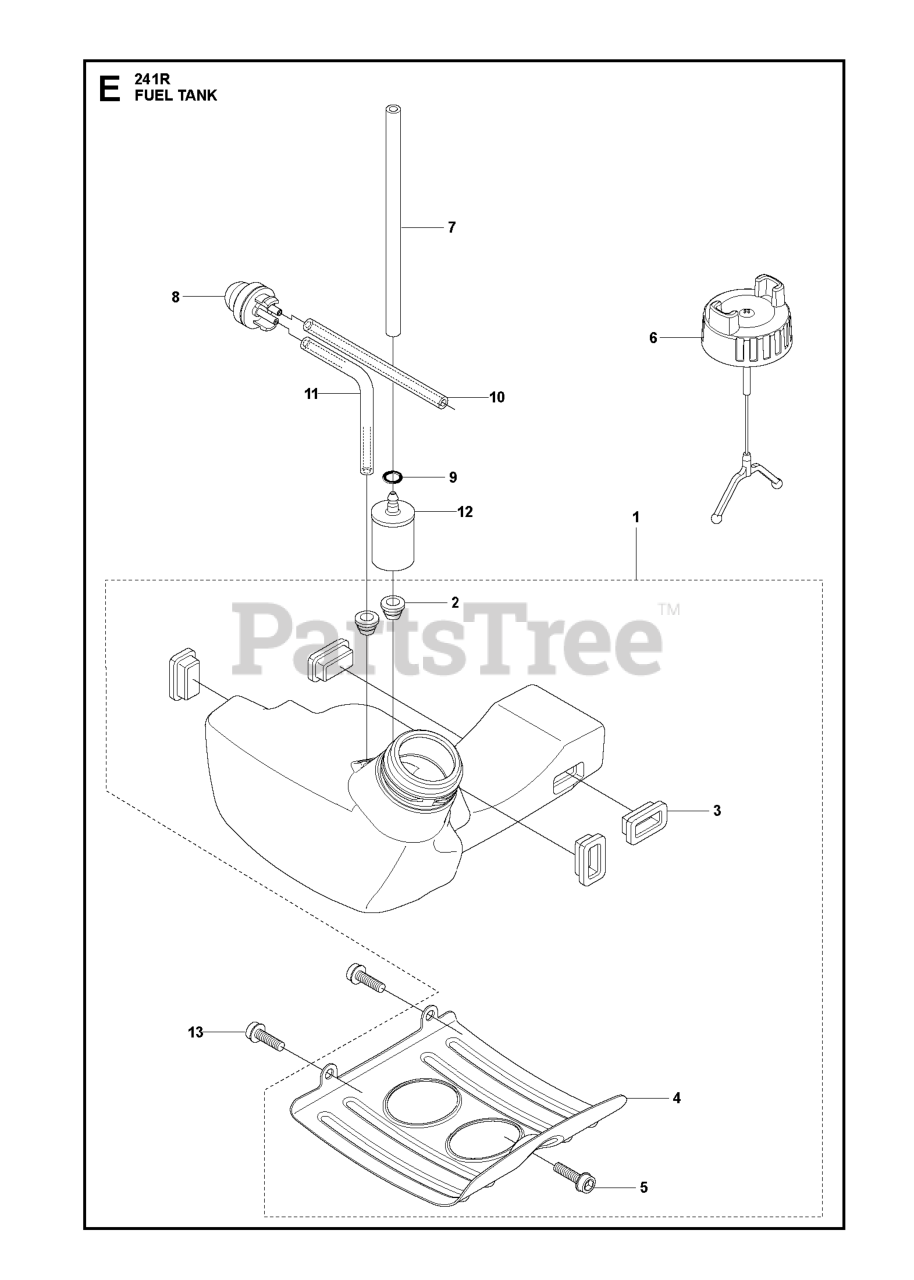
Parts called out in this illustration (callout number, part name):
2	FUEL TANK BUSHING
5	SCREW IHSCFT
6	TANK CAP
8	AIR PURGE BUBBLE
12	RP FUEL FILTER
